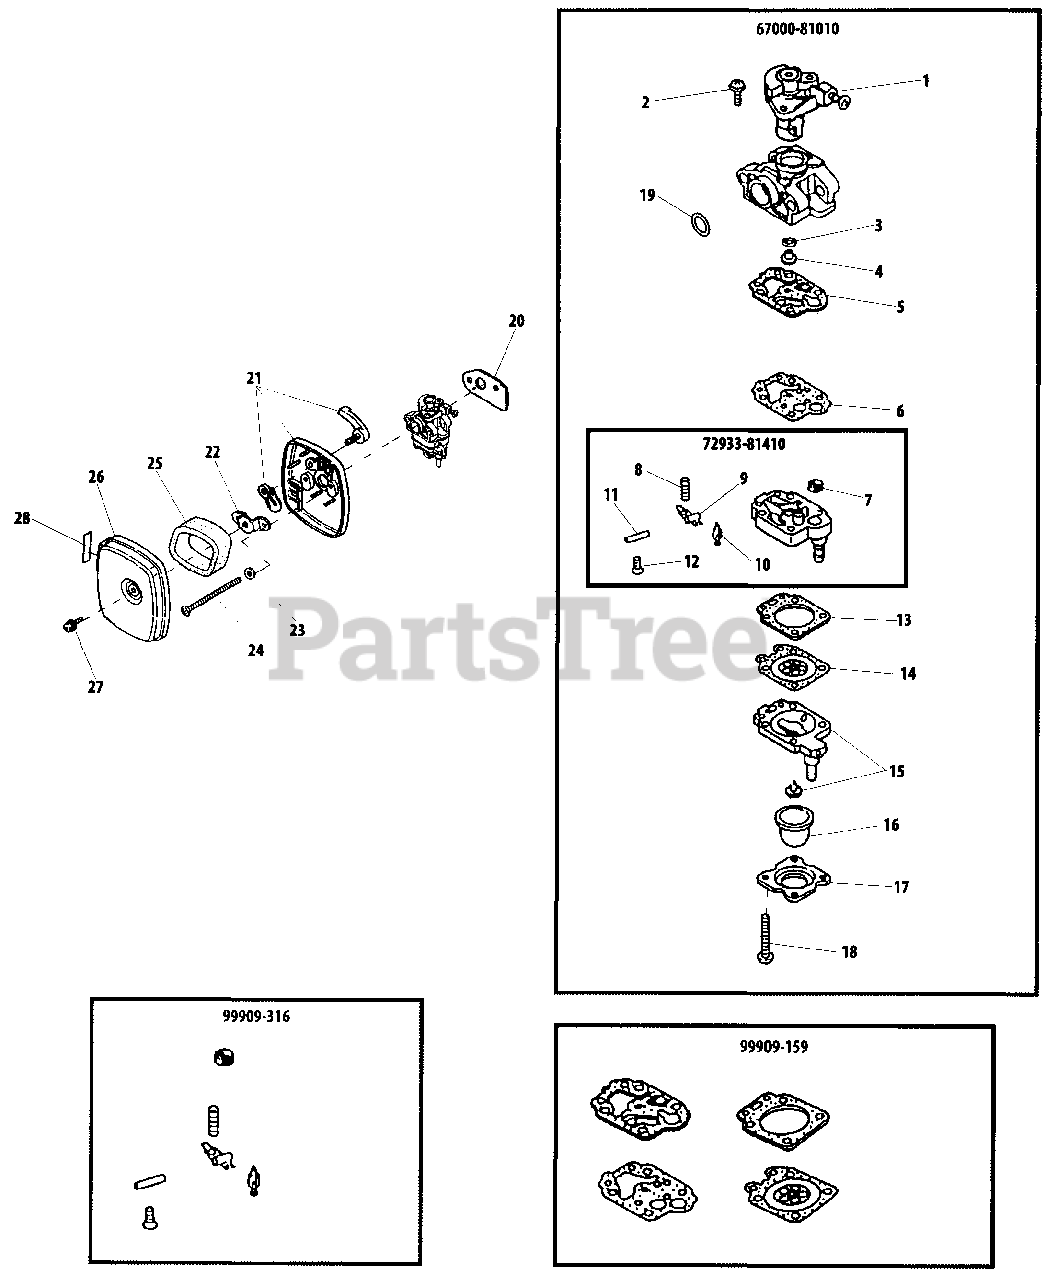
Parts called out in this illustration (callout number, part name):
1	THROTTLE VALVE ASSY
2	SCREW, THROTTLE COLLAR
3	O-RING
4	JET, MAIN #38
5	GASKET, PUMP
6	DIAPHRAGM, PUMP
7	SCREEN, FUEL INLET
8	SPRING, METERING LEVER
9	LEVER, METERING
10	VALVE, INLET NEEDLE
11	PIN, METERING LEVER
12	SCREW
13	GASKET, METERING DIAPHRAGM
14	DIAPHRAGM, METERING
15	BODY ASSY, PURGE
16	BULB, PURGE
17	RETAINER, PURGE BULB
18	SCREW
19	O-RING 15
20	GASKET, INTAKE
21	BASE ASSY, AIR FILTER
22	BRACKET
23	WASHER, FLAT 5.5×10×0.8
24	SCREW
25	FILTER
26	COVER, AIR FILTER
27	SCREW
28	LABEL, CHOKE
67000-81010	CARBURETOR
72933-81410	BODY ASSY, PUMP
99909-159	GASKET / DIAPHRAGM KIT
99909-316	VALVE KIT, INLET NEEDLE
